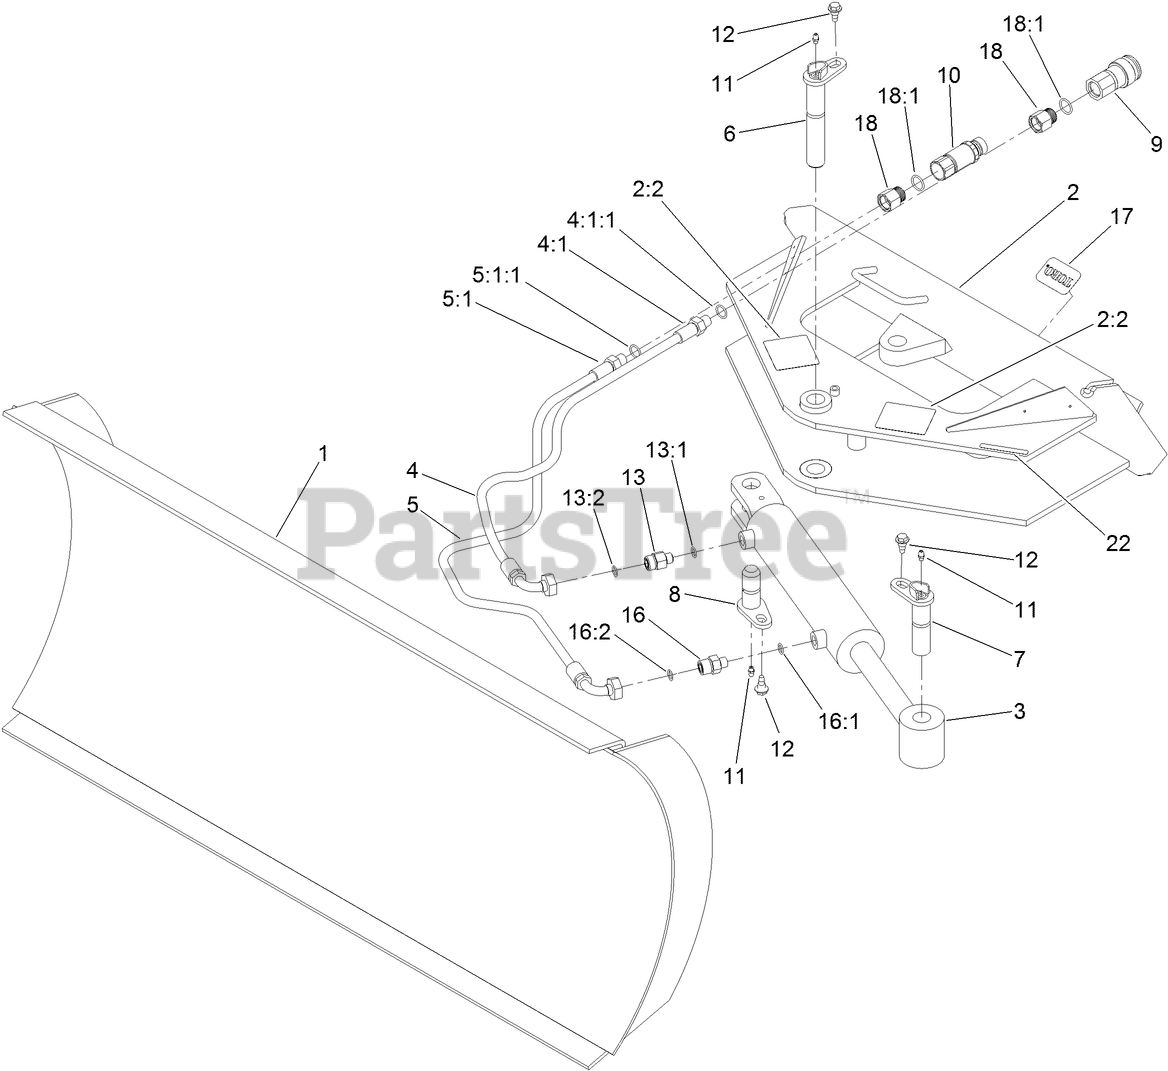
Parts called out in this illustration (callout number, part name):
1	BLADE ASM
2	BLADE PIVOT ASM
2:2	DECAL-WARNING
3	CYLINDER-HYD
4	HYD HOSE ASM
4:1	FITTING-STRAIGHT
4:1:1	O-RING
5	HYD HOSE ASM
5:1	FITTING-STRAIGHT
5:1:1	O-RING
6	PIN-PIVOT
7	PIN-PIVOT
8	PIN-PIVOT
9	COUPLER-FACE, FLUSH
10	NIPPLE-CONNECT, PRESSURE
11	FITTING-GREASE
12	BOLT-SHOULDER
13	FITTING-STRAIGHT
13:1	O-RING
13:2	O-RING
16	FITTING-STR,ORIF
16:1	O-RING
16:2	O-RING
17	DECAL
18	ADAPTER-HYD
18:1	O-RING
22	DECAL-WARNING
